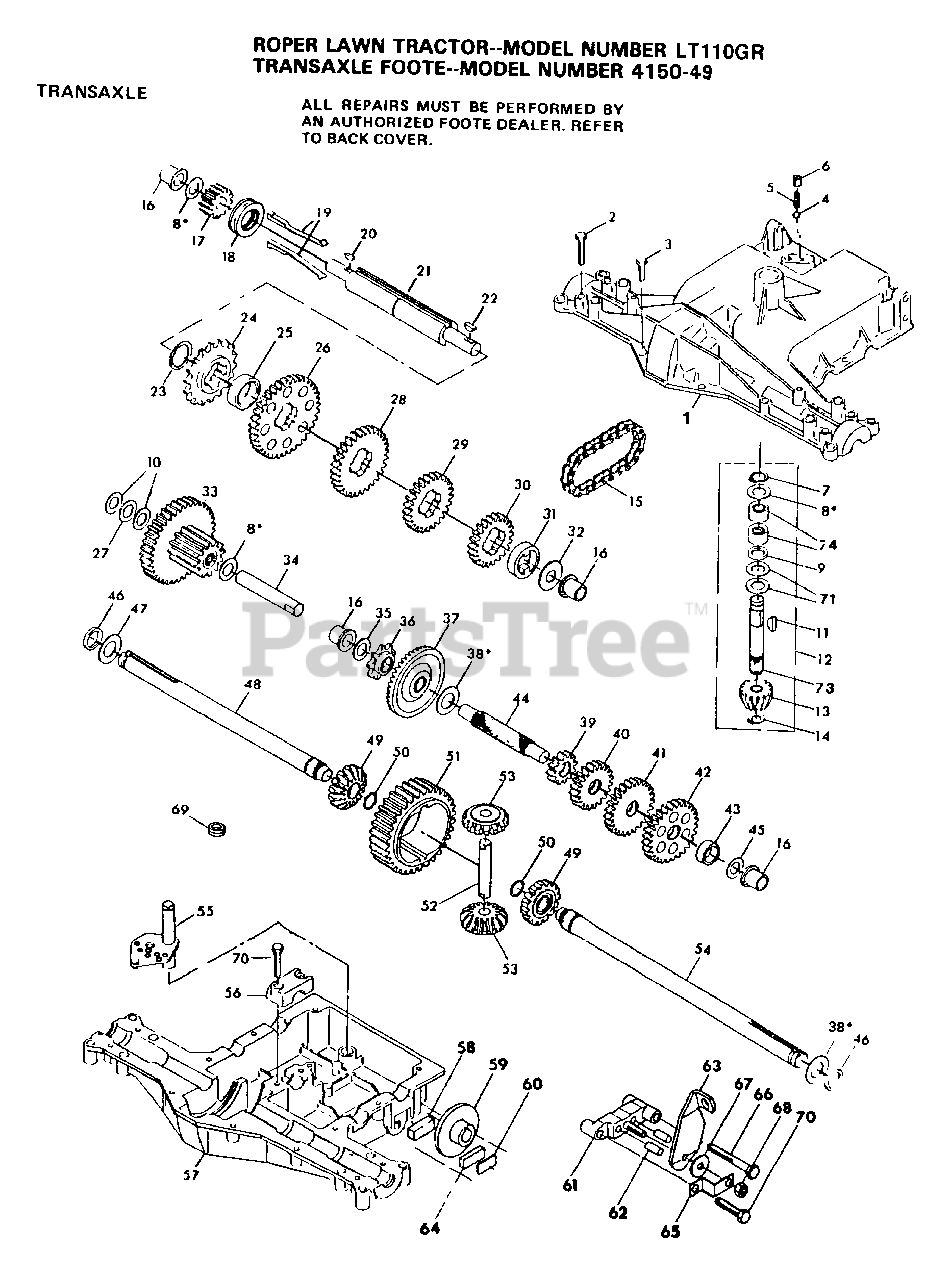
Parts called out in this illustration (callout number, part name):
1	HOUSING, UPPER
2	SCREW 1/4-20 X 1.31
3	SCREW 1/4-20 X .875
4	BALL DETENT
5	SPRING, DETENT
6	SCREW, SET
7	RING RETAINING
8	WASHER PLAIN
8	WASHER, PLAIN .632 X 1.00 X .026
8	WASHER, PLAIN .632 X 1.00 X .060
10	WASHER PLAIN
11	KEY WOODRUFF #9
12	ASSY KIT INPUT SHAFT
13	PINION, BEVEL, 14 TEETH
14	RING, RETAINING
15	CHAIN, 24 PITCHES
16	BEARING, FLANGE
17	GEAR SPUR, 14 TEETH
18	COLLAR CLUTCH
19	KEY, CLUTCH
20	KEY WOODRUFF #3
21	SHAFT, INTERMEDIATE
22	KEY, WOODRUFF, #61
23	RING, RETAINING
24	SPROCKET, 18T
26	GEAR, SPUR, 37 TEETH
27	SPACER .630 X 1.00 X .169
28	GEAR, SPUR, 30 TEETH
29	GEAR, SPUR, 25 TEETH
32	WASHER, PLAIN .640 X 1.37 X .061
33	ASSY GEAR COMB 12&35 TEETH
34	SHAFT, IDLER
35	WASHER PLAIN
36	SPROCKET, 9 TEETH
37	GEAR, BEVEL, 42 TEETH
38	WASHER PLAIN
38	WASHER, PLAIN .758 X 1.25 X .031
39	GEAR, SPUR, 12 TEETH
40	GEAR, SPUR, 20 TEETH
41	GEAR, SPUR, 25 TEETH
42	GEAR, SPUR, 31 TEETH
44	SHAFT, DRIVE
45	WASHER, PLAIN .632 X 1.00 X .060
47	WASHER, PLAIN .758 X 1.25 X .031
49	GEAR, MITER, 15 TEETH
50	RING, RETAINING
51	GEAR, SPUR, 32 TEETH
52	SHAFT, CROSS
53	GEAR, MITER, 15 TEETH
55	ASSY SHIFTER
56	CAP, SUPPORT
57	PUCK, FRICTION
58	PUCK, FRICTION
59	DISC, BRAKE
61	No Desciption for Part
62	PIN, DOWEL
63	LEVER, ACTUATING
64	PUCK, FRICTION
65	BRACKET, ANTI-ROTATION
67	WASHER, PLAIN .321 X 1.00 X .055
68	LOCKNUT 5/16-24
70	SCREW TAPPING
71	WASHER, PLAIN .632 X 1.38 X .046
